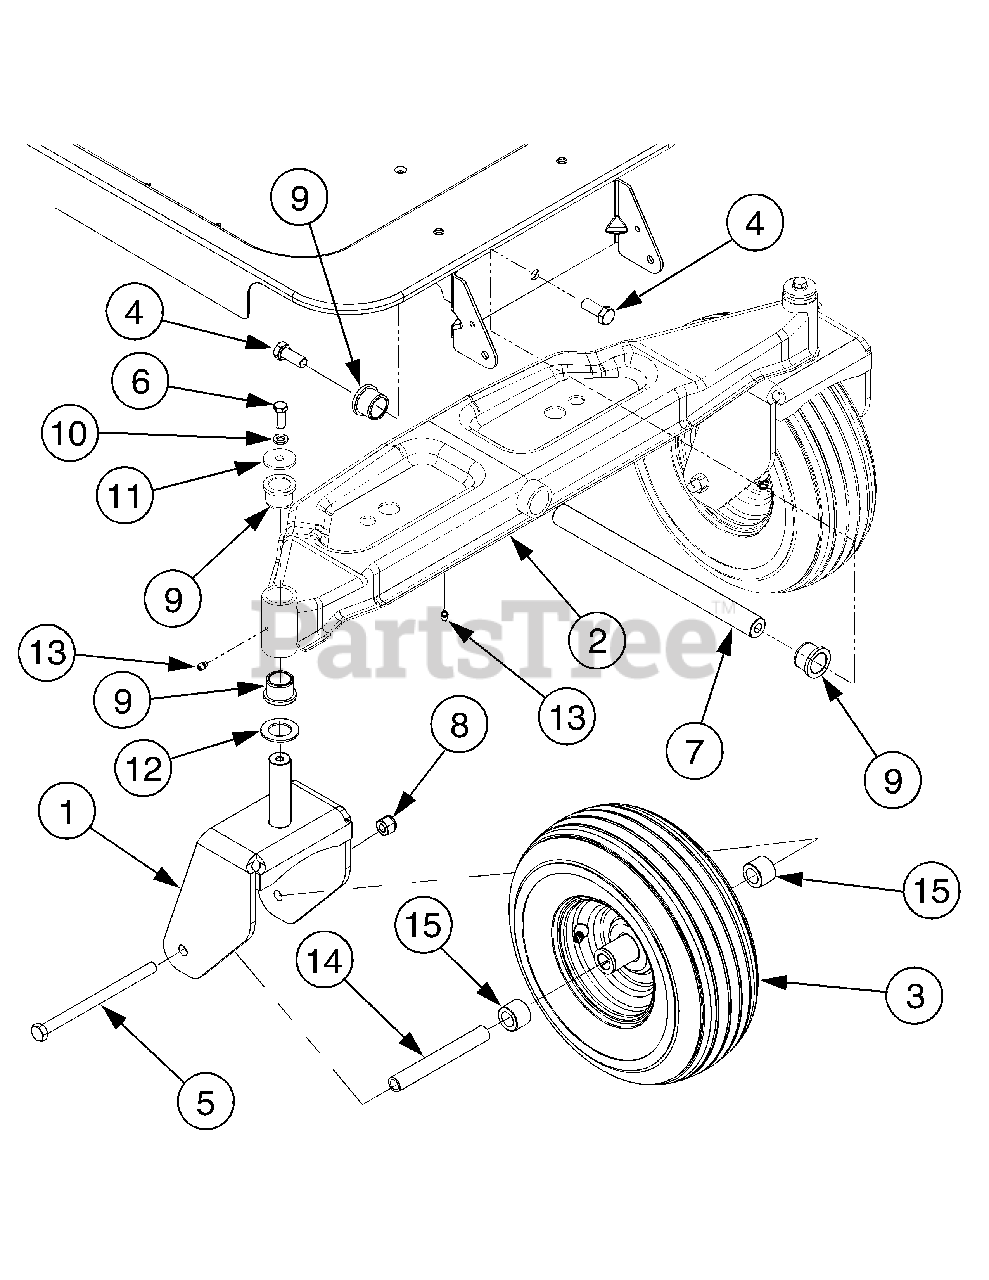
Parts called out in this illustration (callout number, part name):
1	Castor Wheel Bracket
2	Front Pivot Axle
3	Wheel Assembly, 13 x 5-6
4	Hex Lock Screw, 1/2-13 x 1.25
5	Hex Cap Screw, 1/2-20 x 7.25
6	Hex Cap Screw, 3/8-16 x 1.0
7	Axle Shaft
8	Hex Insert Lock Nut, 1/2-13
9	Flange Bearing, 1.0 x 1.246
10	Lock Washer, 3/8
11	Flat Washer, .39 x 1.5 x .134
12	Flat Washer, 1.0 x 1.75 x .10
13	Lube Fitting, 3/16 Drive
14	Spacer, .51 x .75 x 5.825
15	Hub, .76 x 1.23 x .92
